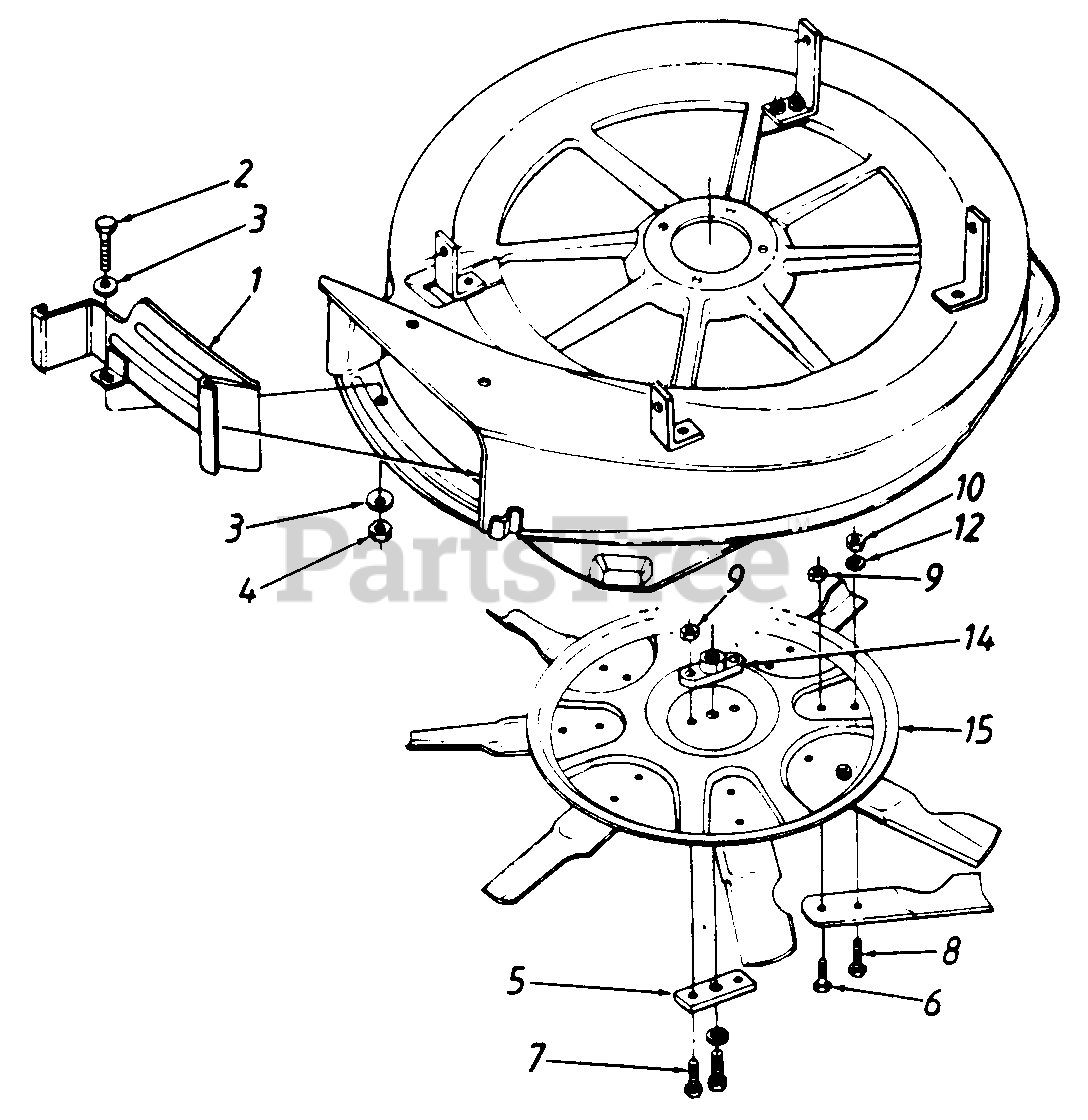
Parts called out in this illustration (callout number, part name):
1	Mulching Baffle Ass'y.
2	Hex Bolt 5/16-18 x .5"
3	Bell-Wash. .325" I.D.
4	Hex L-Nut 5/16-18 Thd.
7	Hex Bolt 5/16-24 x 1.25" Lg. (Gr. 5)
8	Hex Bolt 3/8-24 x .88" Lg.
9	Hex L-Nut 5/16-24 Thd.
10	Hex L-Nut 3/8-24 Thd. (Gr. 5)
12	Fl-Wash. .406" I.D. x .75"
14	Blade Adapter
15	30" Mulching Blade Disc
